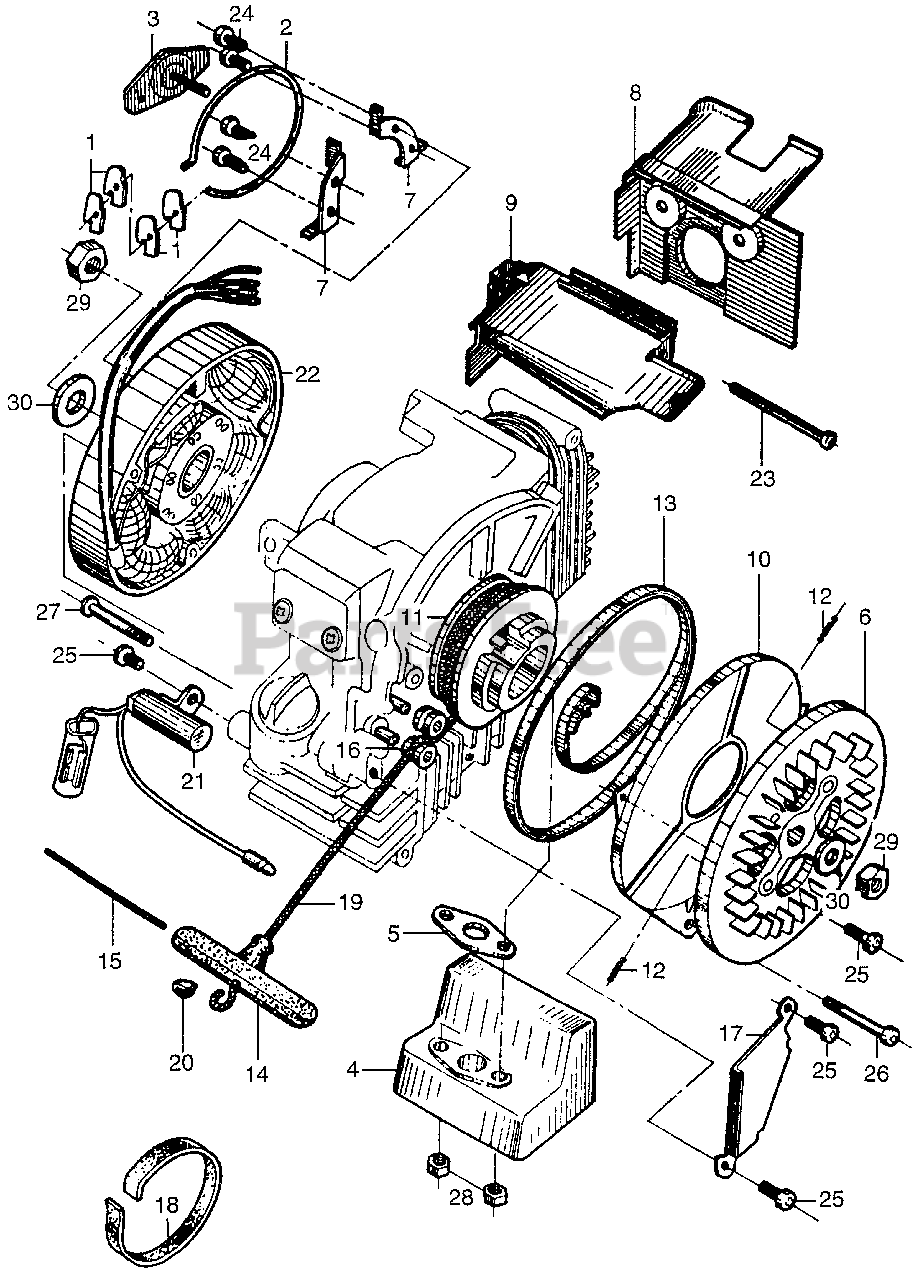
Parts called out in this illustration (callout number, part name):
1	WEIGHT, GOVERNOR (NOT AVAILABLE)
2	RING, GOVERNOR WEIGHT (NOT AVAILABLE)
3	SLIDER, GOVERNOR (NOT AVAILABLE)
4	MUFFLER (NOT AVAILABLE)
5	GASKET, MUFFLER (NOT AVAILABLE)
6	FAN, COOLING (NOT AVAILABLE)
7	FAN, GENERATOR (NOT AVAILABLE)
8	VANE A, GUIDE (NOT AVAILABLE)
9	VANE B, GUIDE (NOT AVAILABLE)
10	CASE, SPRING (NOT AVAILABLE)
11	PULLEY, STARTER (NOT AVAILABLE)
12	SPRING, STARTER PAWL (NOT AVAILABLE)
13	SPRING, STARTER RETURN (NOT AVAILABLE)
14	GRIP, STARTER (NOT AVAILABLE)
15	SHAFT (3MM) (NOT AVAILABLE)
16	ROLLER, STARTER ROPE (NOT AVAILABLE)
17	HOLDER, ROLLER (NOT AVAILABLE)
18	SEAT, OIL (NOT AVAILABLE)
19	ROPE, STARTER (NOT AVAILABLE)
20	PIPE, JOINT (NOT AVAILABLE)
21	CONDENSER (NOT AVAILABLE)
22	ALTERNATOR (NOT AVAILABLE)
23	SCREW, TANK SETTING (NOT AVAILABLE)
24	SCREW, PAN (5X6)
25	SCREW, PAN (5X10)
26	SCREW, PAN (5X32)
27	SCREW, PAN (6X30)
28	NUT, HEX. (5MM) (NOT AVAILABLE)
29	NUT, HEX. (8MM)
30	WASHER, PLAIN (8MM)
